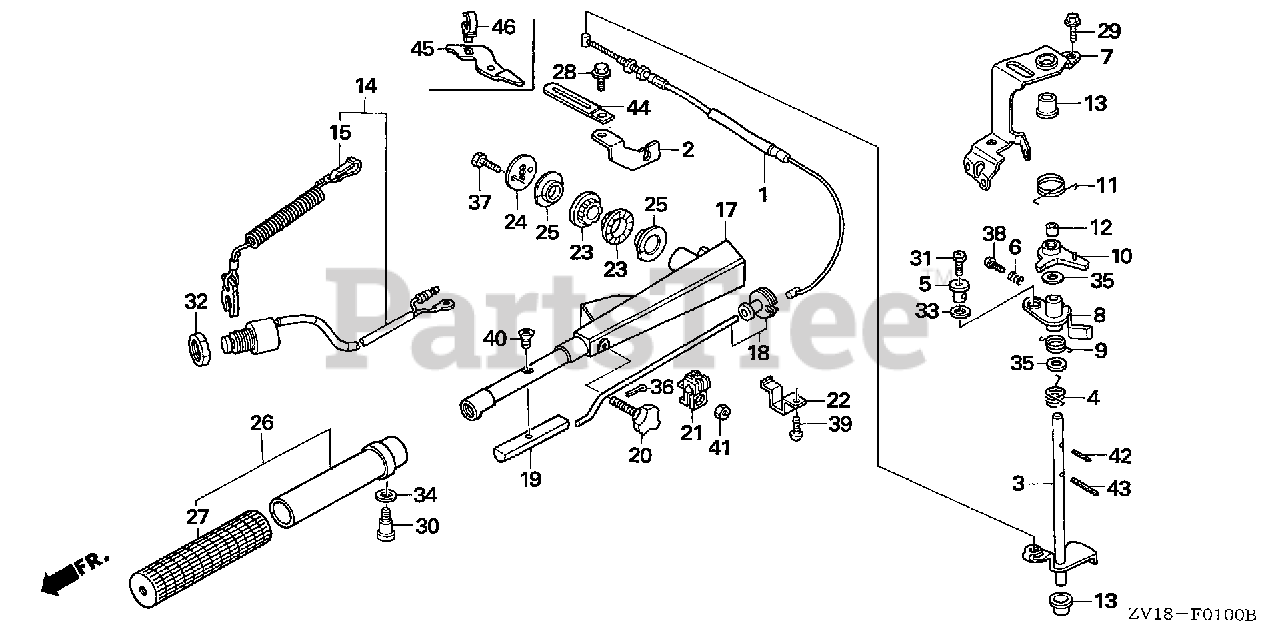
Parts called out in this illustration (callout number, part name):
1	CABLE, THROTTLE
2	HOLDER, CABLE
3	SHAFT, THROTTLE
4	SPRING, THROTTLE ARM
5	HOLDER, THROTTLE ROD
6	SPRING, THROTTLE ADJUSTING
7	STAY, THROTTLE SHAFT
8	LINK, THROTTLE
9	SPRING, RETURN
10	POWL, NEUTRAL START
11	SPRING, POWL
12	COLLAR, POWL
13	BUSH, SHAFT
14	SWITCH ASSY., EMERGENCY STOP
15	WIRE, EMERGENCY
17	HANDLEBAR *NH282MU* (OYSTER SILVER METALLIC-U)
18	REEL, THROTTLE
19	WEIGHT, HANDLEBAR
20	BOLT, FRICTION
21	BLOCK, THROTTLE FRICTION
22	STAY A, THROTTLE REEL
23	RUBBER, HANDLE MOUNTING
24	PLATE, HANDLEBAR
25	COLLAR, HANDLEBAR
26	PIPE, GRIP
27	RUBBER, GRIP
28	BOLT, FLANGE (6X14) (CT200)
29	BOLT, FLANGE (6X14) (CT200)
30	BOLT, PIPE GRIP
31	BOLT, RECESSED (5X8)
32	NUT, HEX. (16MM)
33	WASHER, NYLON (9MM)
34	WASHER (7.5MM)
35	WASHER, PLAIN (10MM)
36	PIN, SPLIT (2.0)
37	BOLT, HEX. (6X16)
38	SCREW, PAN (4X16)
38	SCREW, PAN (4X20) (NOT AVAILABLE)
39	SCREW, PAN (5X12)
40	SCREW, OVAL (6X12)
41	NUT, HEX. (6MM)
42	PIN, SPRING (3X18)
43	PIN, SPRING (3X32)
44	CLIP B, CORD
45	STAY, FUEL TUBE
46	CLAMP, WIRE (8MM)
46	CLAMP, CARBURETOR SOLENOID WIRE HARNESS
